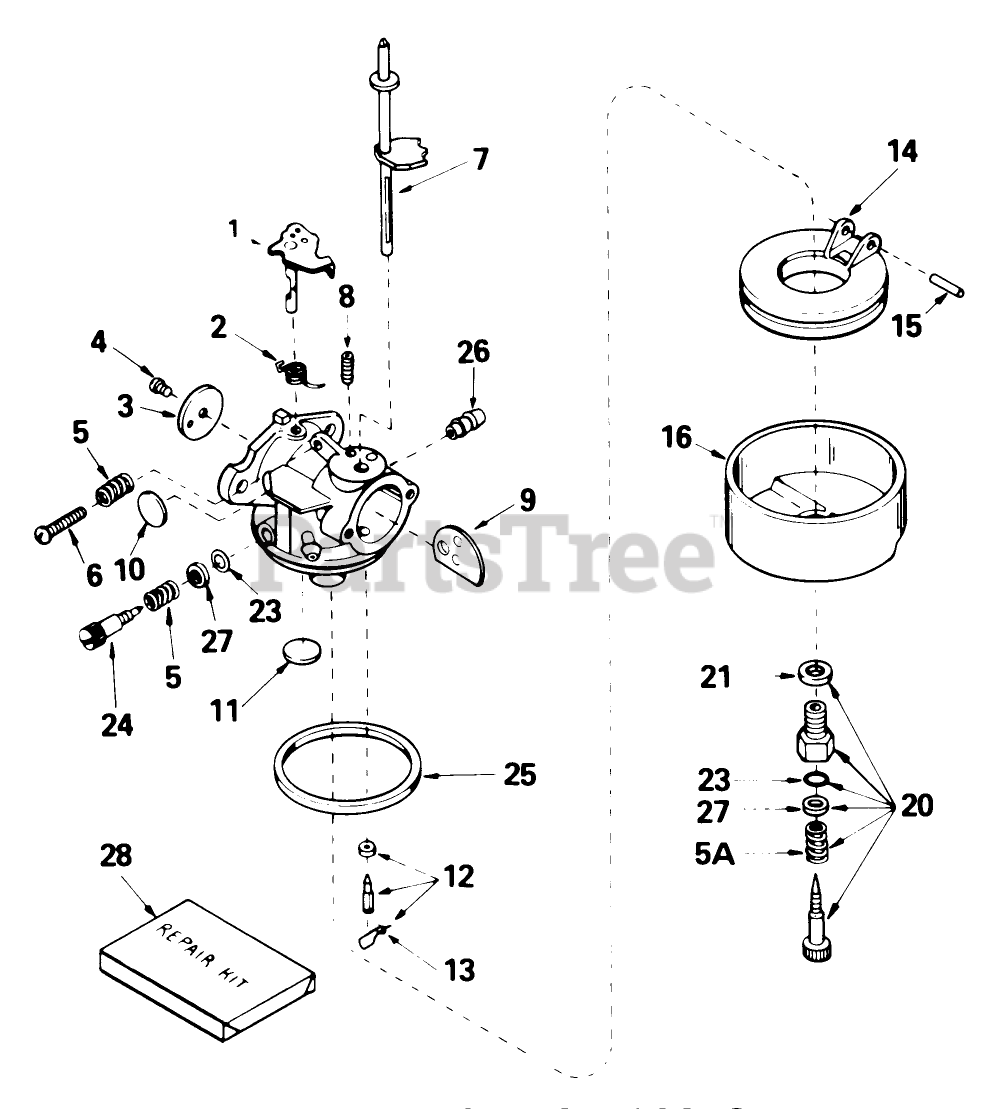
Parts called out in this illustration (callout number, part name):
1	Shaft/Lever-Throttle
2	Spring-Return, Throttle
3	Shutter-Throttle
4	Screw-Shutter
5	Spring-Tension
5A	Spring
6	Screw-Throttle Crack Screw / Idle Speed
7	Shaft-Choke
8	Spring-Positioning, Choke
9	Shutter-Choke
10	Plug-Welch, Idle Mixture Well
11	Plug-Welch, Atmospheric Vent
12	Inlet Needle, Seat Clip Assy. (Incl. No. 13)
13	Clip-Spring
14	Float
15	Shaft-Float
16	Bowl-Float (no drain)
20	Adjustment Screw Assy., Main (Incl. Nos. 5A, 21 23)
21	Washer-Bowl Nut
23	ORing
24	Screw-Idle
25	O Ring-Bowl, Float
26	Fitting-Fuel
27	Washer
28	Repair Kit (Incl. items marked *)
